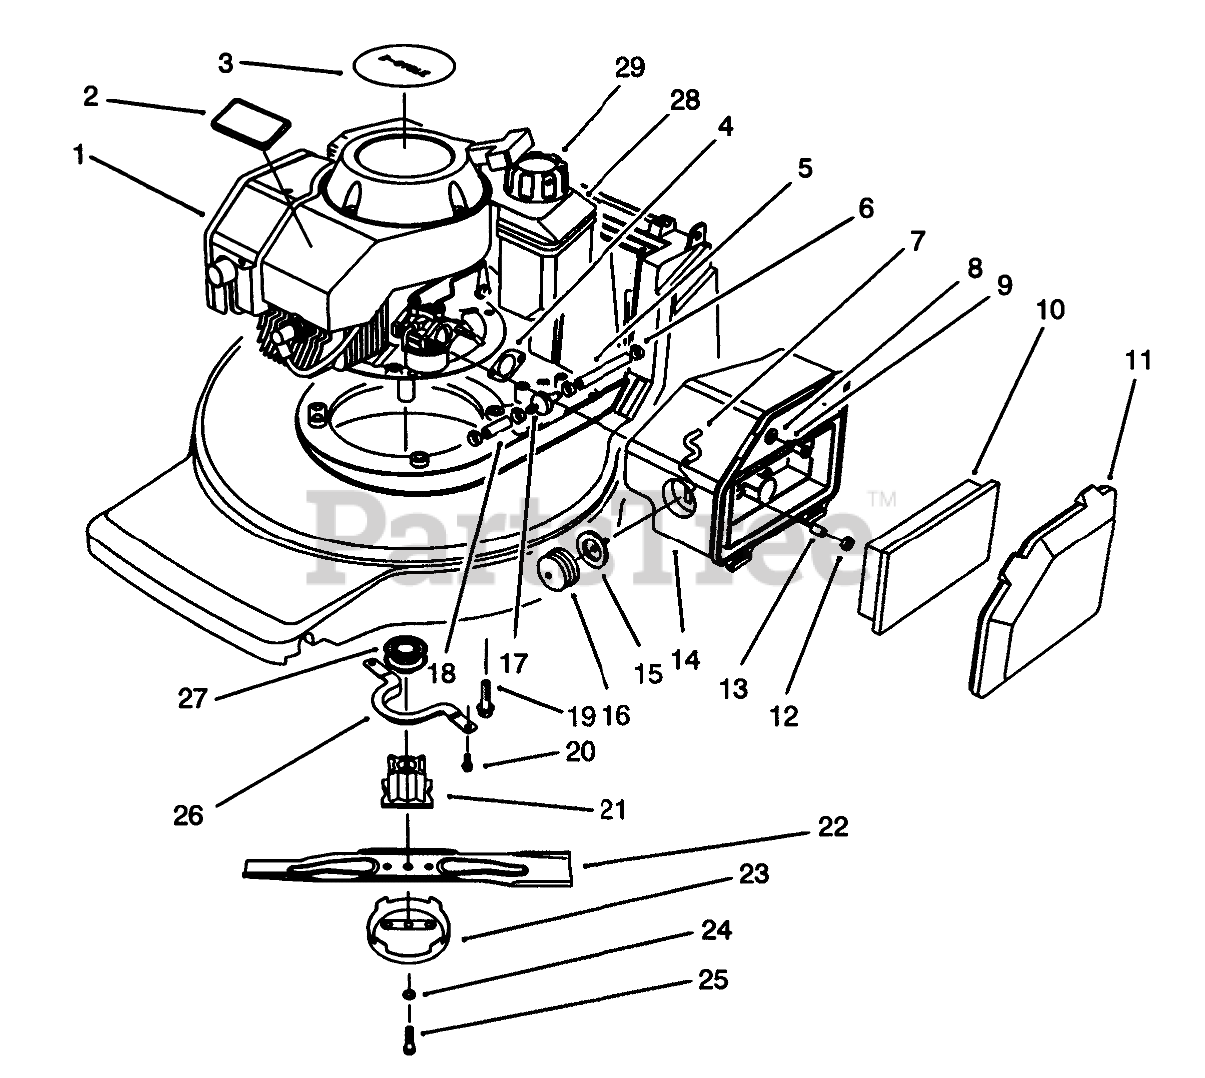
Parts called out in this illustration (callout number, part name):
1	ENGINE 121CC INT'L 2CYC
2	TORO LOGO PLT
3	DECAL- 2 CYC RECOIL
4	GASKET-AIR CLEANER
5	HOSE-FUEL
6	CLAMP-FUEL LINE
7	HOSE-PRIMER
8	WASHER-FLAT
9	SCREW-HH
10	ELEMENT-AIR CLEANER
11	COVER-AIR CLEANER
13	SPACER
14	BODY-AIR CLEANER
15	BODY-PRIMER
16	BULB-PRIMER
17	FILTER-FUEL
18	HOSE-FUEL
19	SCREW-HHF
20	SCREW-HWH
21	BLADE RETAINER - 25 MM
22	Blade-48cm
23	CUP-SCALP, ANTI
24	WASHER-LOCK
25	BOLT-BLADE
26	Guide-Belt
27	PULLEY-DRIVE, ZONE START
28	FUEL TANK ASM
29	GAS CAP ASM
